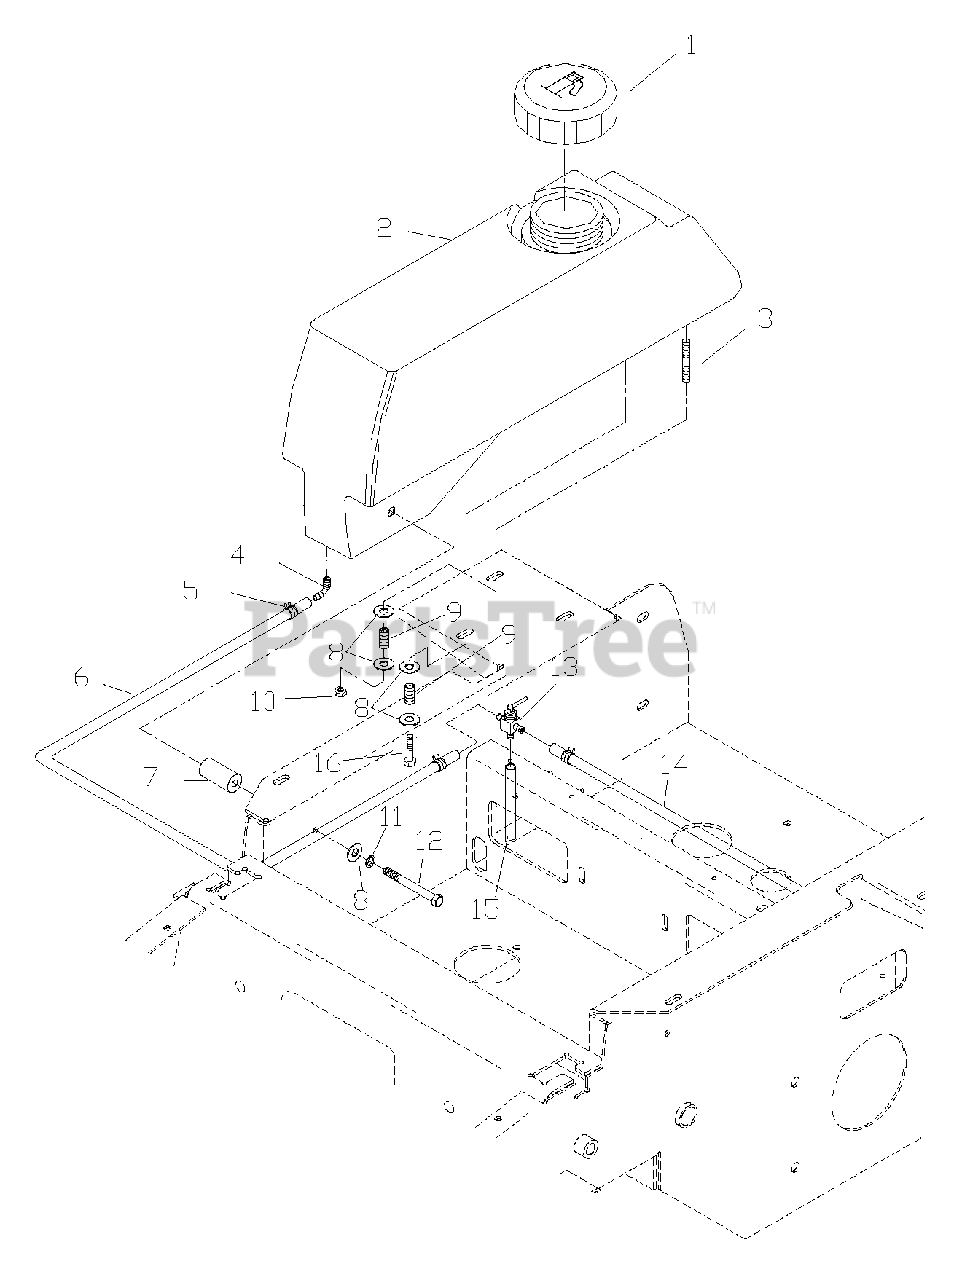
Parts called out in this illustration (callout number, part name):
1	FUEL CAP
2	FUEL TANK RT.
2	FUEL TANK LT.
5	HOSE CLAMP
7	TANK SPACER
8	WASHER 5/16 FLAT
10	NUT 5/16 NYLOC
11	WASHER 5/16 LOCK
12	HCS 5/16 X 4.0
13	FUEL VALVE
15	FUEL LINE KAWASAKI
15	FUEL LINE KOHLER
16	HCS 5/16 X 1.0
